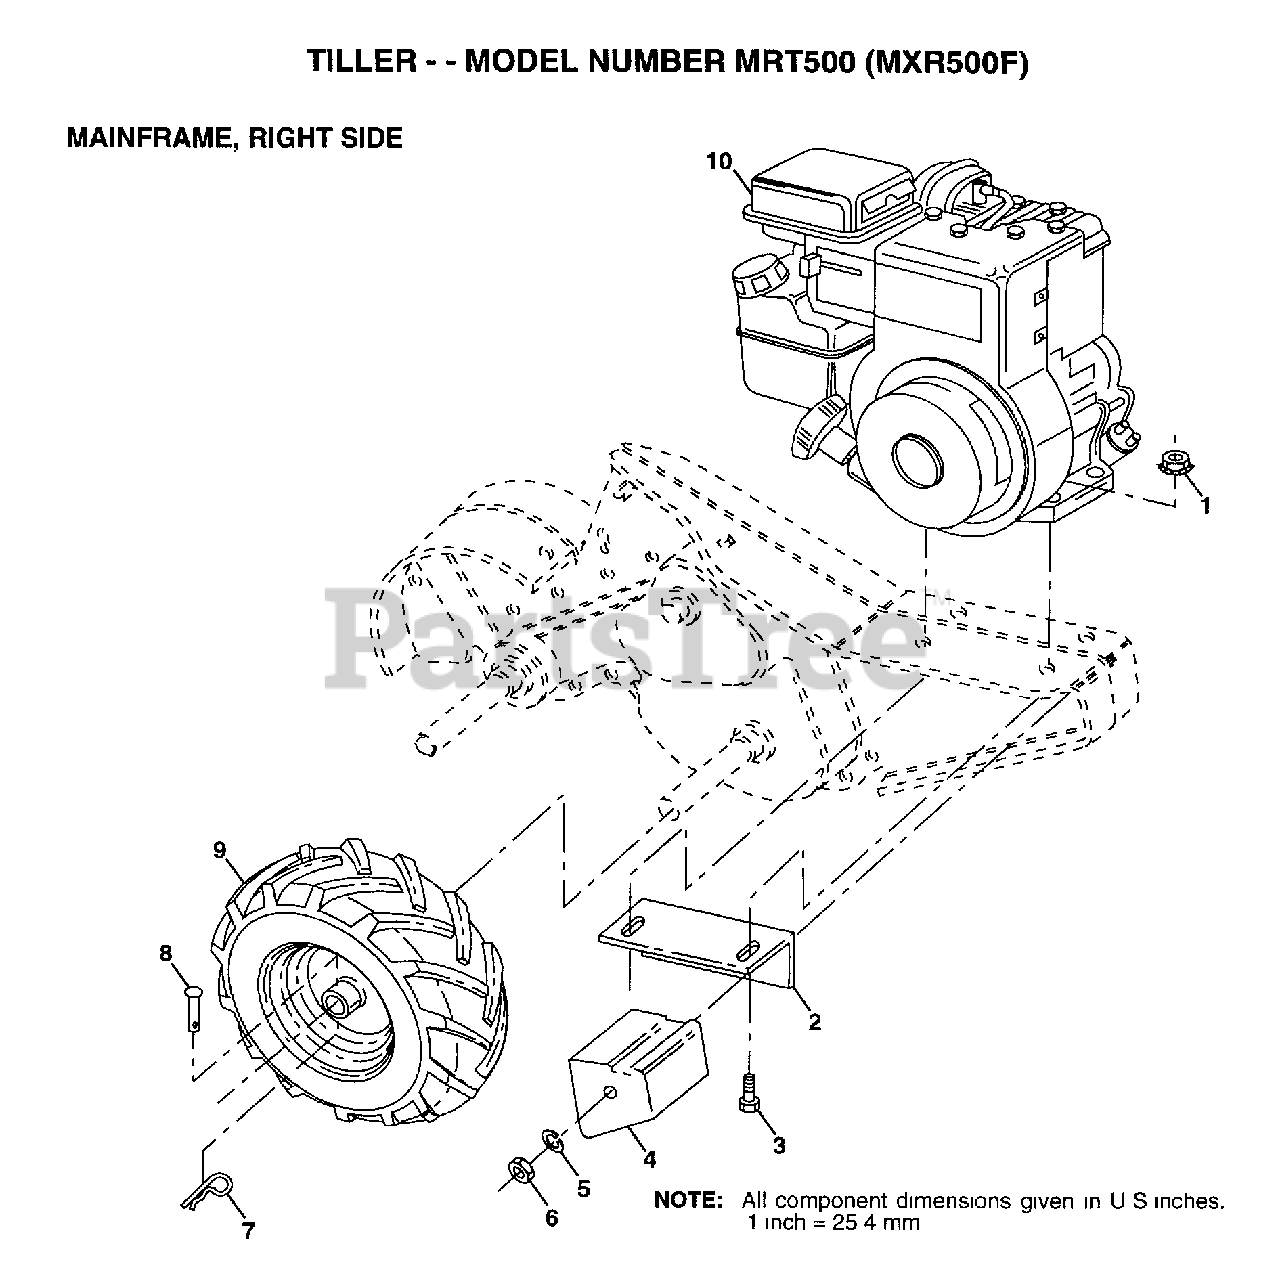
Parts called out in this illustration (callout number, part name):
2	BRACKET RH CRT
3	BOLT.HEX.5/16-1.5
4	COUNTERWEIGHT CRT
5	LOCKWASHER
6	NUT.HEX.3/8-16UNC
7	RETAINER M
8	RIVET.DRILL.1.75
9	TIRE.CHV.13X5.0-6
